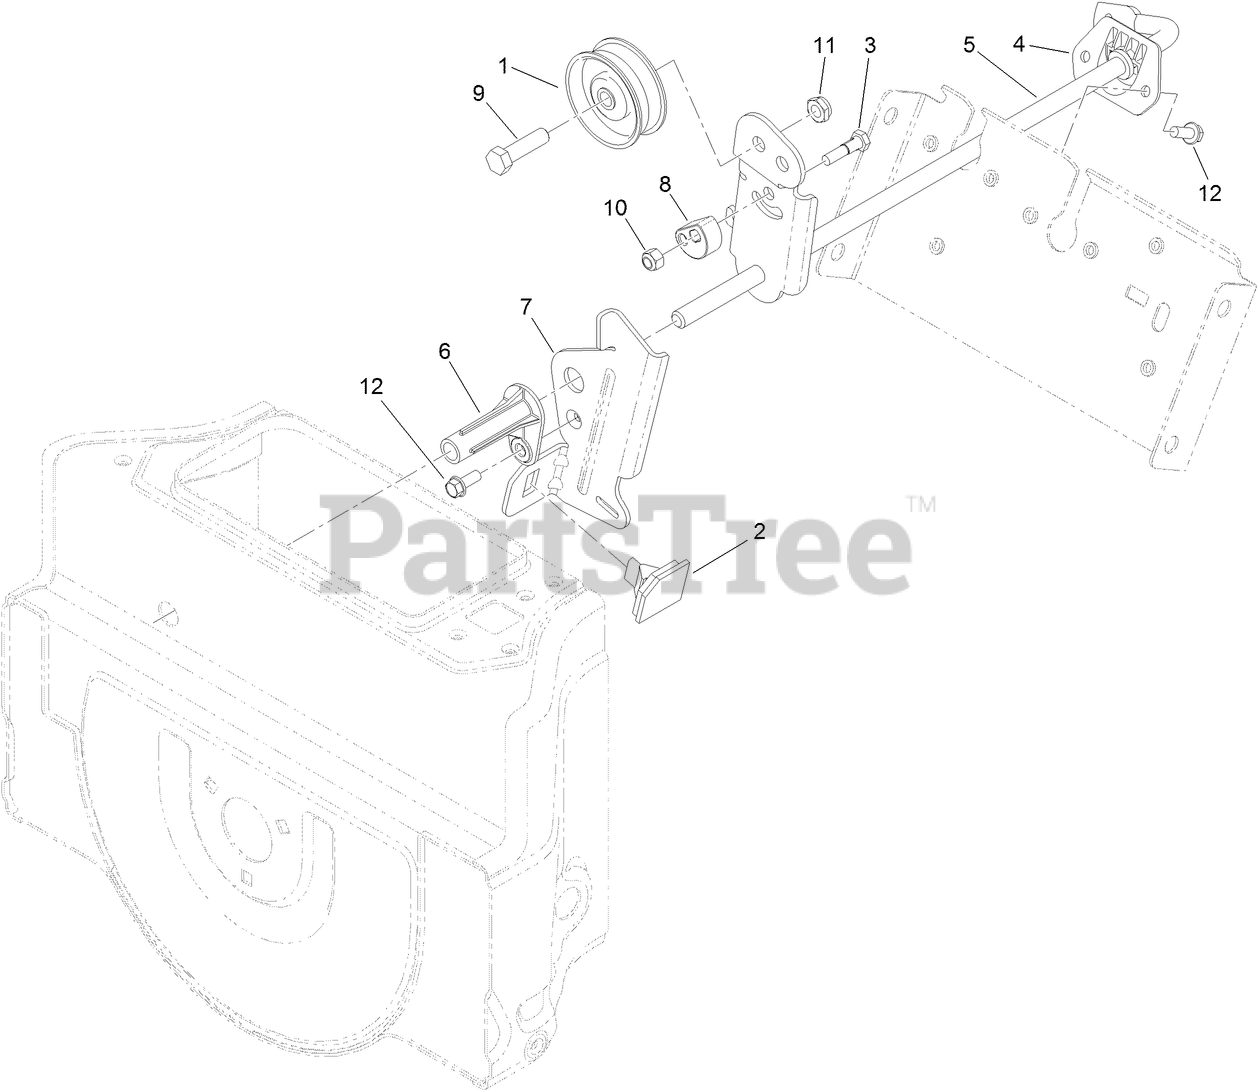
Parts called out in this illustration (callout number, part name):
1	PULLEY-IDLER
2	PAD-BRAKE
3	BOLT-PIVOT, ECCENTRIC
4	BUSHING-ROD, CLUTCH
5	IMPELLER CLUTCH ASM
6	PIVOT-BRAKE, IMPELLER
7	ARM-BRAKE, IMPELLER
8	ECCENTRIC-BRAKE, IMPELLER
9	SCREW-HH
10	NUT-LOCK, NI
12	SCREW-HWH
